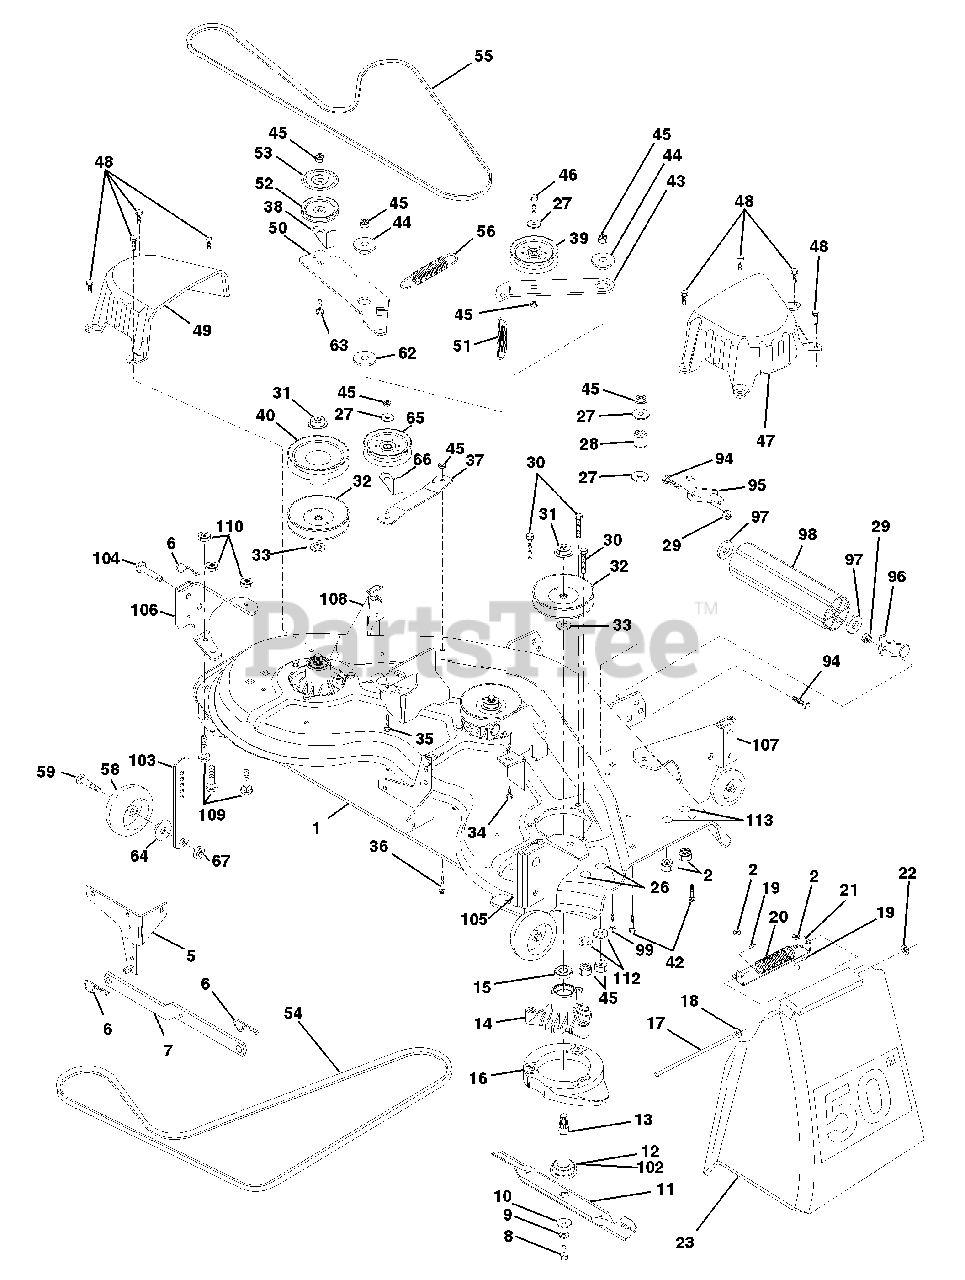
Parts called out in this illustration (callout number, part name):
1	Deck Asm., Mower 50" Vented
2	Nut, Crownlock 5/16-18 Unc
5	Bracket Asm., Sway Bar
6	Retainer, Spring
7	Arm Suspension, Rear
8	Bolt 3/8-24 x 1.25 Gr. 8 Patched
9	Washer, Lock Hvy 3/8 Unplated
10	Washer, Hard Blade Mower Vented
11	Blade (3 Required)
12	Bearing, Ball #6204 (Mandrel)
13	Shaft Asm., W/Lower Brg
14	Housing, Mandrel 50" Vent
15	Bearing, Ball Mandrel
16	Stripper, Mower Vented
17	Rod, Hinge
18	Washer 11/32 x 5/8 x 16 Ga.
19	Cap, Sleeve
20	Spring, Torsion Deflector
21	Bracket, Deflector
23	Shield, Deflector Mower
27	Washer 13/32 x 13/16 x 16 Ga.
28	Spacer, Spring Stop Idler
29	Nut, Lock Hex W/Wsh 3/8-16 Unc
30	Screw Tdhrolling Washer Head
31	Nut, Flg Top Lock Cntr 9/16
32	Pulley, Mandrel
33	Washer, Spacer Mower Vented
34	Bolt, Carriage 3/8-16 x 1-1/4
35	Bolt, Carriage 3/8-16 x 2
36	Bolt, Carriage 3/8-16 x 1 Gr. 5
37	Stiffener, Arm Idler
38	Keeper, Belt Idler
39	Pulley, Idler Flat
40	Pulley, Driven
42	Bolt, Carriage 5/16-18 Unc x 3/4
43	Arm, Idler Secondary
44	Spacer, Retainer
45	Nut, Crownlock 3/8-16 Unc
46	Bolt, Fin Hex 3/8-16 Unc x 1-3/4
47	Cover, Mandrel RH
48	Screw, Thd Roll 1/4-20 x 5/8
49	Cover, Mandrel LH
50	Arm, Idler Primary
51	Spring, Secondary
52	Pulley, Idler V Groove
53	Shield, Idler
54	V-Belt, Mower Primary
55	V-Belt, Mower Secondary
56	Spring, Primary
58	Wheel, Gauge
59	Bolt, Shoulder
62	Washer Hardened
63	Bolt Carriage 3/8-16 x 1-1/2
64	Washer 3/8 x 7/8 x 14 Ga.
65	Pulley Idler Flat Mower
66	Keeper, Belt Idler 44/50" Vent
67	Nut, Center Lock 3/8-16
94	Bolt, Fin Hex 3/8-16 UNC x 1
95	Bracket, Asm. Noseroller LH
96	Bracket, Asm. Noseroller RH
97	Washer 17/32 x 7/8 x 16 Ga.
98	Roller, Nose
99	Bolt, Carriage 3/8-16 x 1-3/4 Gr. 5
102	Washer Felt
103	Bar Pnt Adjusting Wheel Gauge
104	Pin Head Rivet
105	Bracket Whl Ga. Asm Rear RH 50"
106	Bracket Whl Ga. Asm. Rear LH 50"
107	Bracket Whl Ga. Asm. Front RH 50"
108	Bracket Whl Ga. Asm Front LH 50"
109	Bolt Carriage 5/16-18 x 5/8 Blk
110	Nut Crownlock 5/16-18 Blk
111	Bolt Rd Hd Sht Sqnk 3/8-16 x 3/4
112	Washer 17/32 x 3/4 x 16 Ga.
113	Bolt Carriage 5/16-UNC x 1/2
